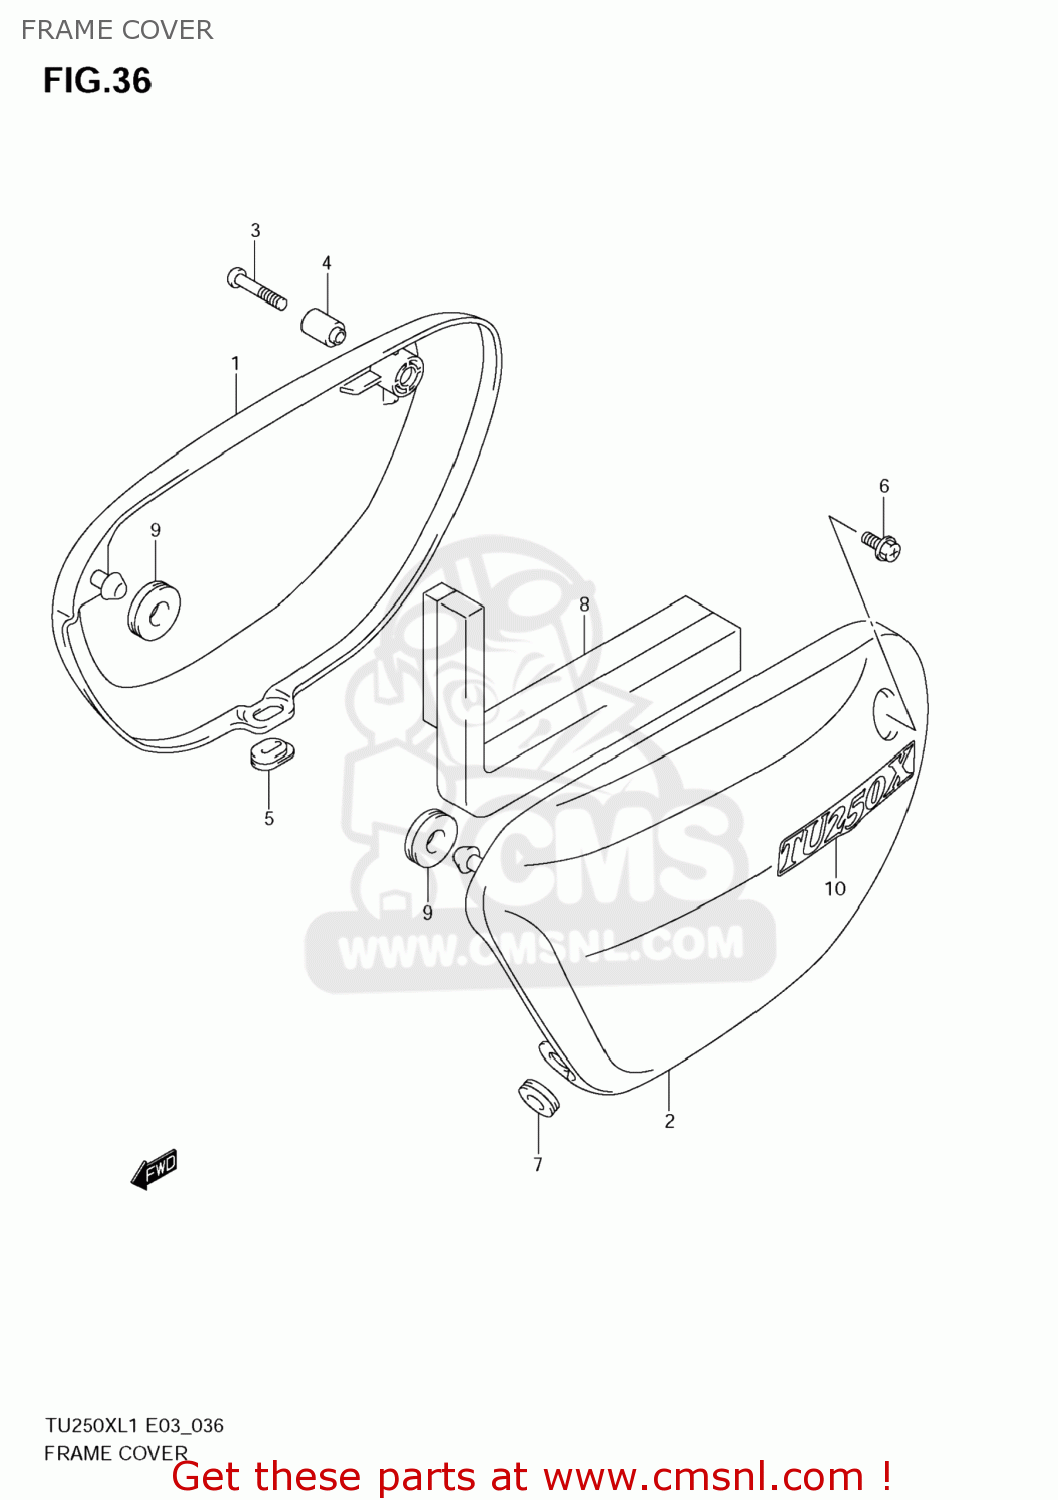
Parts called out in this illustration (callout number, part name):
1	COVER,FRAME,R(GRAY)
2	COVER,FRAME,L(GRAY)
3	SCREW(6X35.5)
4	SPACER(6.2X9X23.5)
5	CUSHION
6	BOLT(6X16.5)
7	CUSHION
8	CUSHION,FRAME COVER
9	CUSHION
10	EMBLEM,FRAME COVER
